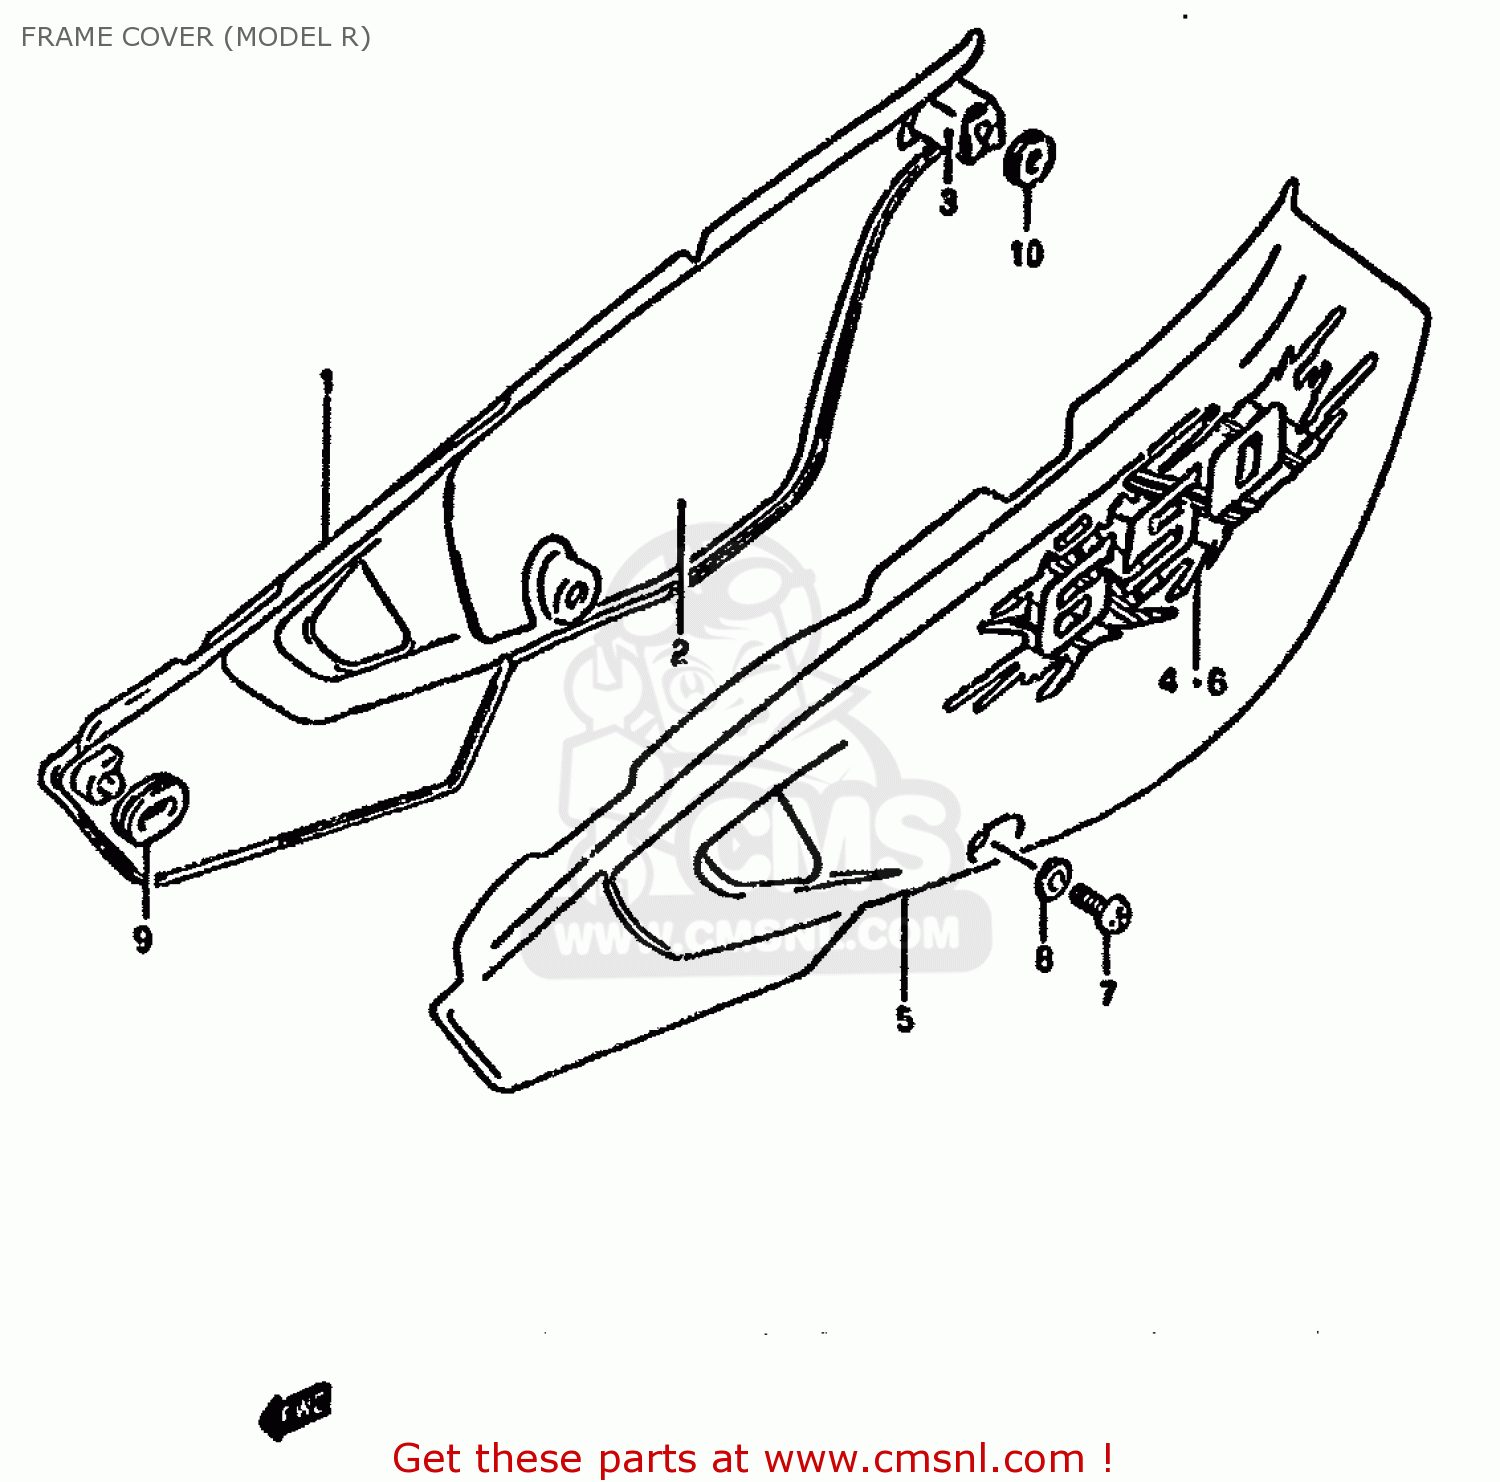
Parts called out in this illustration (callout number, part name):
1	COVER,FRAME,RIGHT
2	SHIELD,FRAME COVER,R
3	SHIELD,FRAME COVER,R NO.2
4	TAPE,LH
5	COVER,FRAME,L(WHITE)
6	TAPE,LH
7	SCREW
8	WASHER
9	CUSHION
10	CUSHION
11	TAPE,LH
12	COVER,FRAME,LEFT
13	EMBLEM,LH
14	TAPE,FRAME COVER NO.2
15	SCREW
16	WASHER
17	CUSHION
18	CUSHION
19	CUSHION
